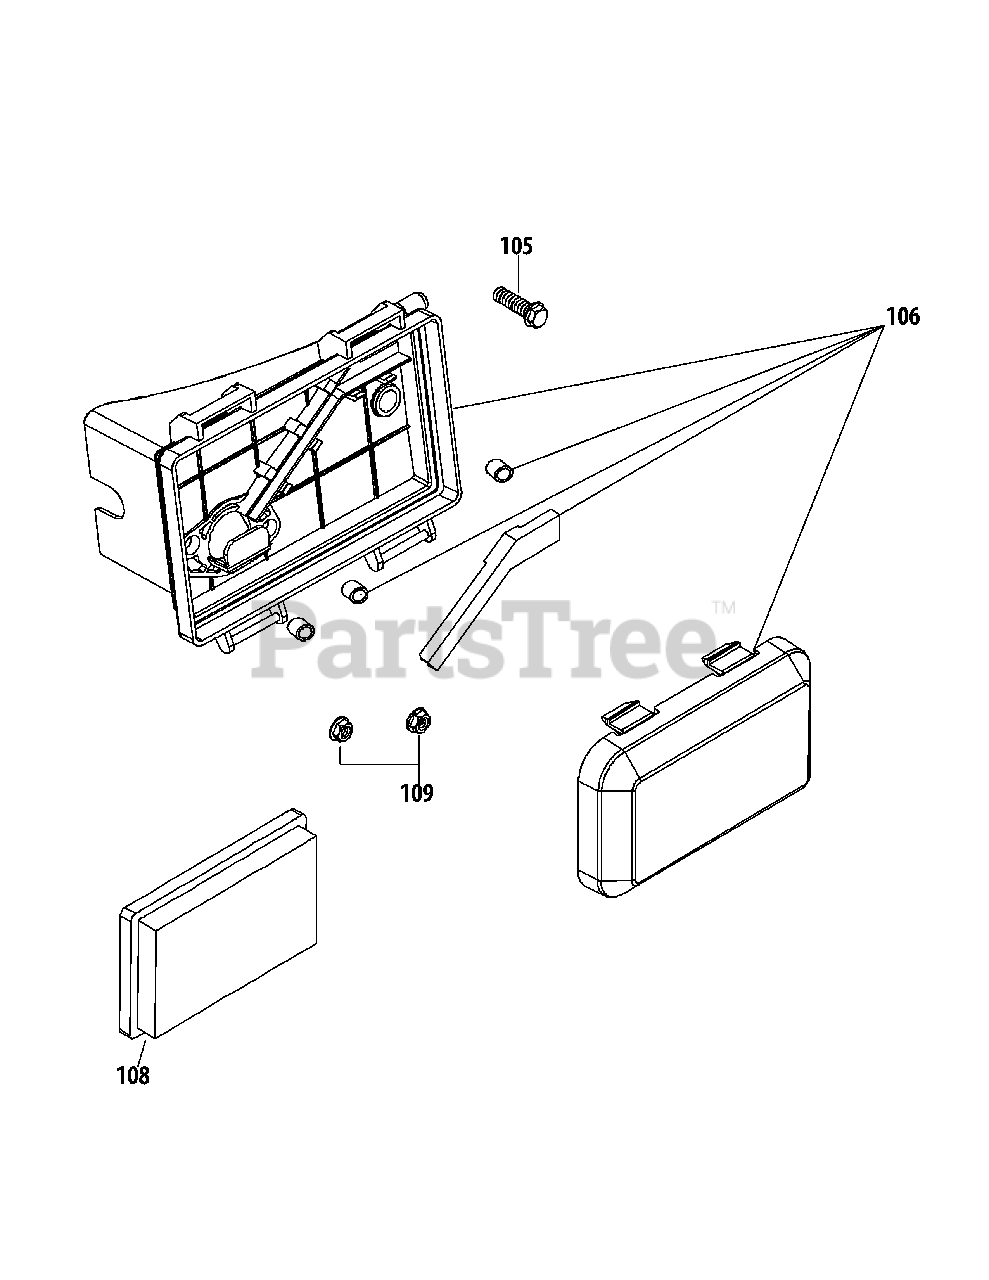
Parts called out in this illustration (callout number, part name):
105	Bolt M6X30 Af Base/Coil/E-Starter
106	Air Cleaner Housing Ass'Y
108	Air Filter
109	Nut M6X10Mm Starter/Carb/Muff
